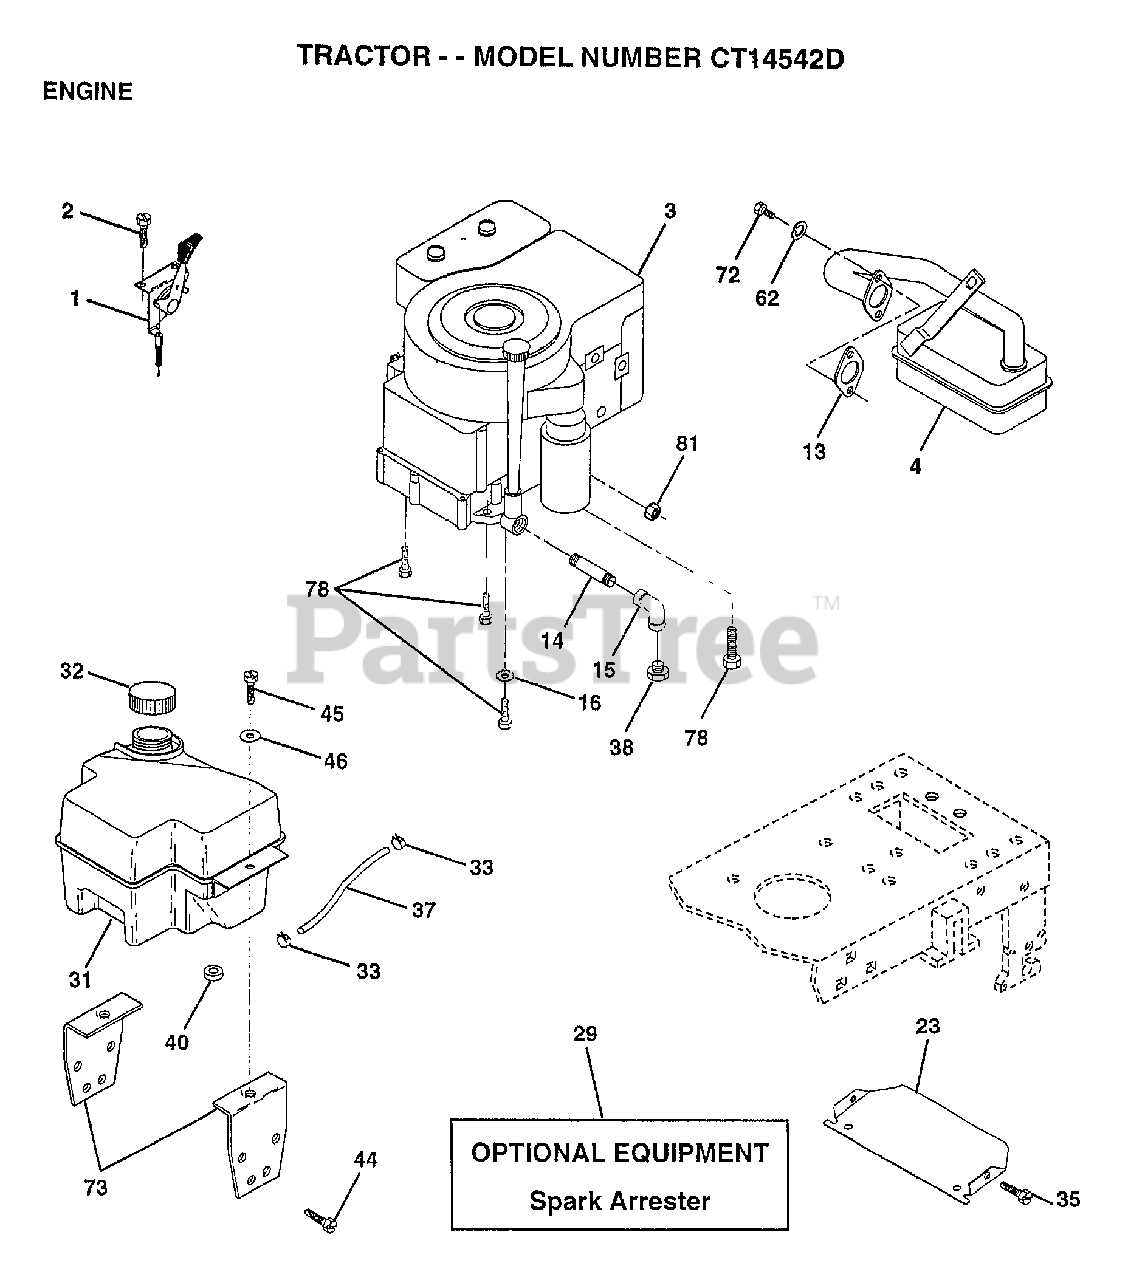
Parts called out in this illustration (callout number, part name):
1	CONTROL.THTL.19.6
2	SCREW LT
3	ENGINE B&S
4	MUFFLER
13	GASKET ENG 1 313 LD TIN PLATED
14	PIPE NIPPLE
15	ELBOW
16	LOCKWASHER
23	SHIELD-HEAT
32	CAP ASM FUEL
33	HOSE CLAMP
35	SCREW
37	LINE FUEL
44	SCREW
45	SCREW HEX CRT
46	WASHER
62	LOCKWASHER
72	SCREW
73	BRACKET.SUPT.TANK
78	SCREW
81	NUT
